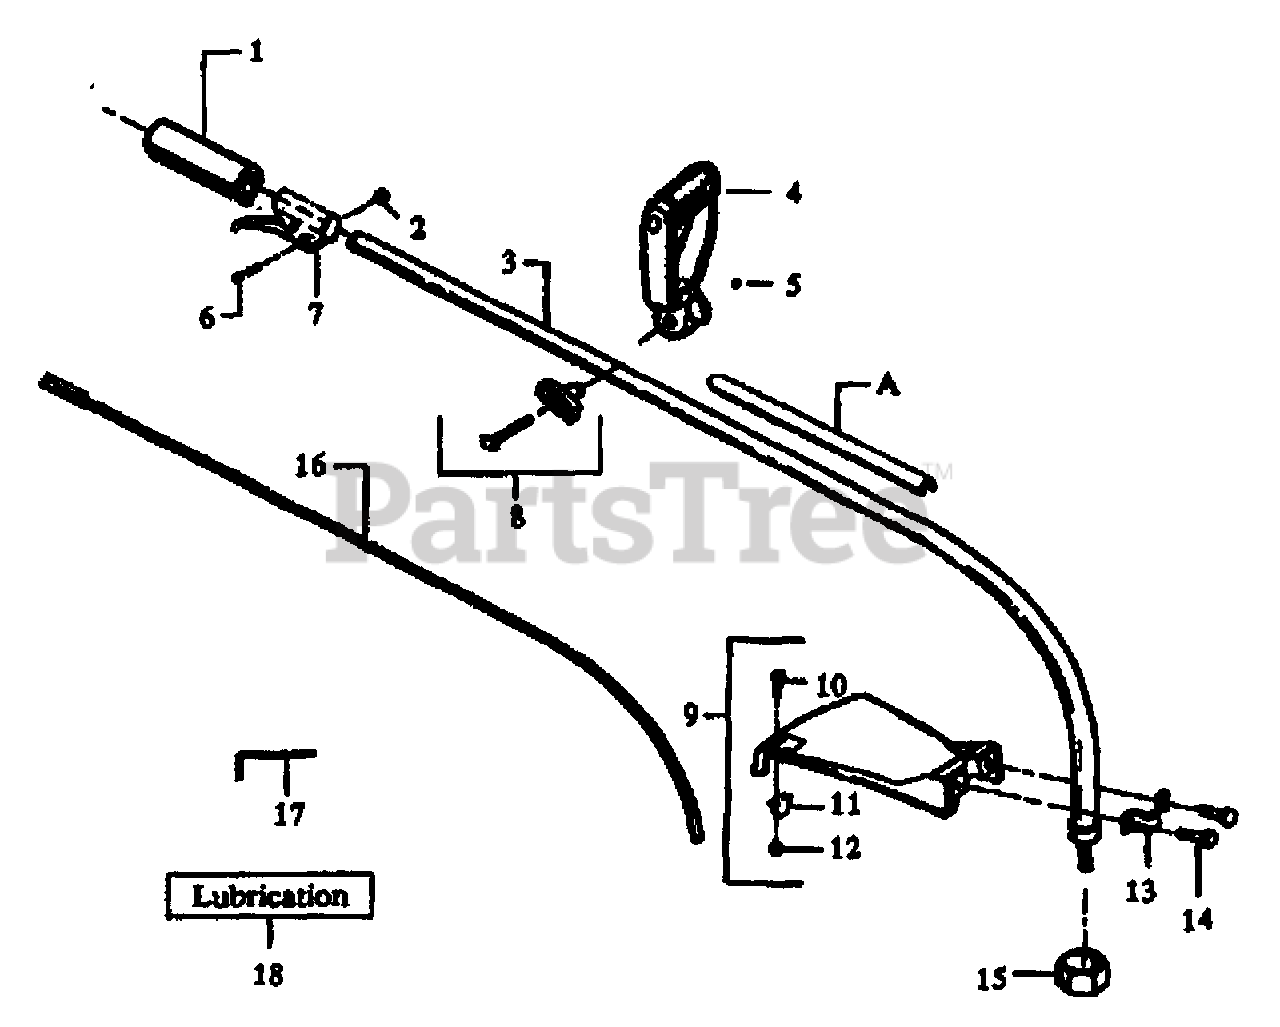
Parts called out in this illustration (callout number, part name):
1	Grip
3	Drive Shaft Housing
4	Handle Ass'y.
7	Throttle Housing Ass'y.
8	"T" Handle Kit
9	Shield Kit Ass'y.
11	Line Limiter
12	Locknut
13	Shield Bracket
14	Screw
16	Drive Shaft
17	Hex Wrench (5/32)
18	Shaft Lubrication
A	Shaft Warning Decal
